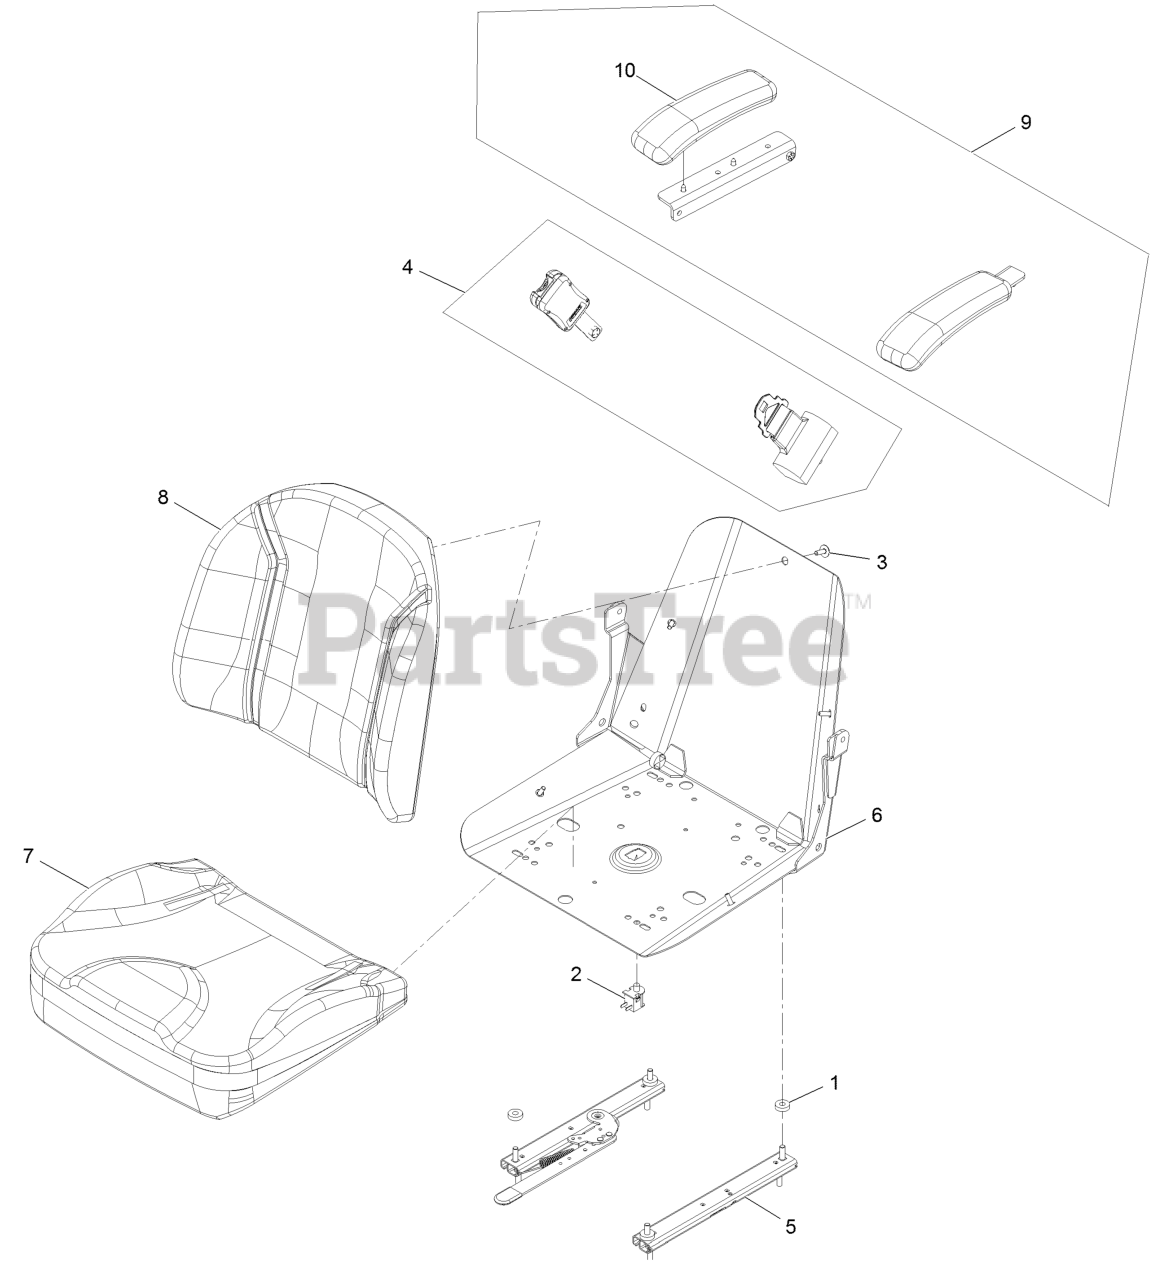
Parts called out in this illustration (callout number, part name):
1	Spacer-Pin, Mounting
3	Screw-HWH 1/4-20 X 3/4 Taptite
4	Kit-Seat Belt
5	ASM-Seat Track Svc
6	Frame-Seat Svc
7	Cover-Seat Bottom Svc
8	Cushion-Seat, Back
9	Armrest Kit
10	Cushion-Rest, Arm
